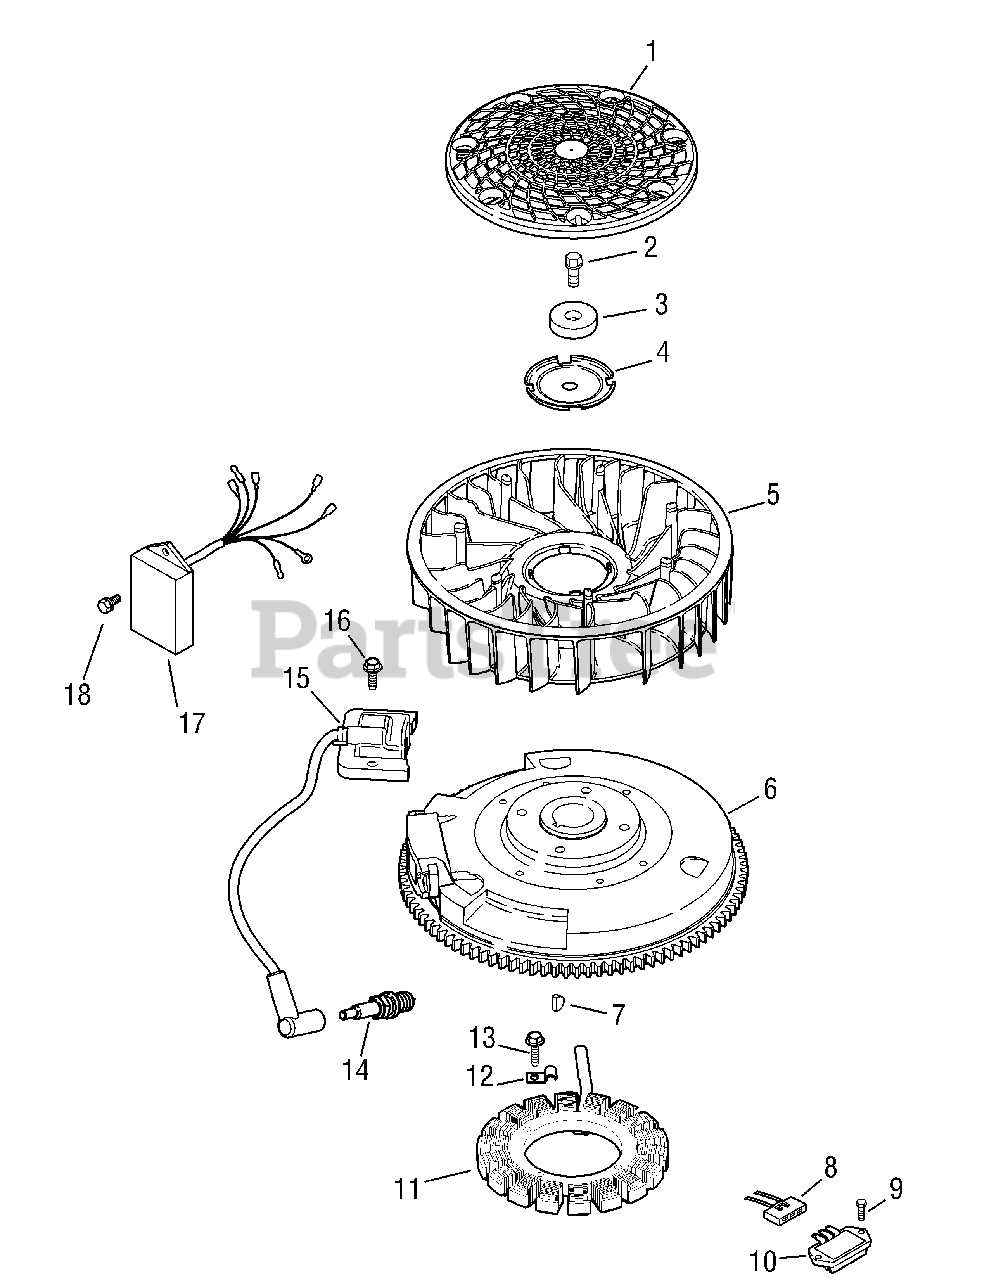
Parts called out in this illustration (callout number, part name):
2	Hex Flange Screw, M10 x 1.5 x 45
4	Fan Mounting Plate
5	Fan
6	Flywheel
8	Rectifier - Regulator
9	Connector (3 Contact)
10	Hex Flange Screw, M5 x 0.8 x 16
11	15 Amp Stator Kit
13	Hex Screw, M5 x 0.8 x 25
14	Spark Plug
15	Ignition Module
16	Hex Flange Screw, M5 x 0.8 x 20
17	Speed Advance Module
18	Hex Flange Screw, M4 x 0.7 x 10
